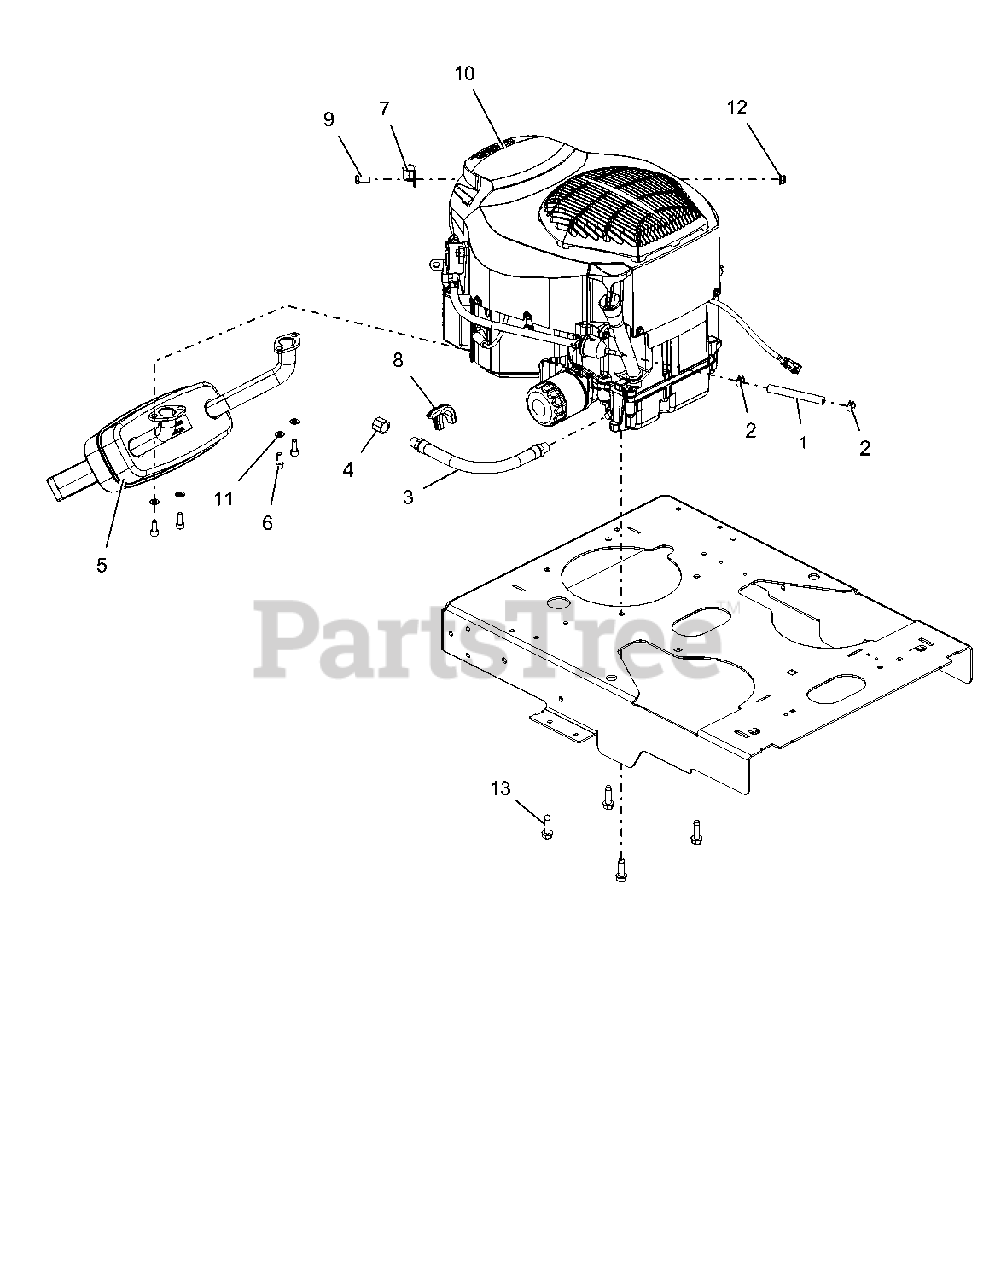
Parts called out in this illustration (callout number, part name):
1	.25 LOW-PERM GAS HOSE 21.50" LG - TANK TO ENGINE
2	CLAMP, FUEL LINE
3	HOSE, HYD .38-11-OK M6N0-M6N0
4	PIPE, CAP 3/8 NPT FEMALE
5	MUFFLER, KOHLER
6	SCR, CAP SOCKET HEAD
7	CLAMP, CUSHIONED STEEL .75
8	PROTECTOR, OIL DRAIN HOSE
9	BLT-HEX .31-18X.75 GR5 YWZC
10	ENGINE-KOHLER TWIN-24-PRO W/SC
11	WSHR-LK .31X.078 REG YWZC
12	NUT-LK-NYL-FLG .31-18 YWZC
13	SCR-TAP .38-16X1.25 HWH TR YZ
